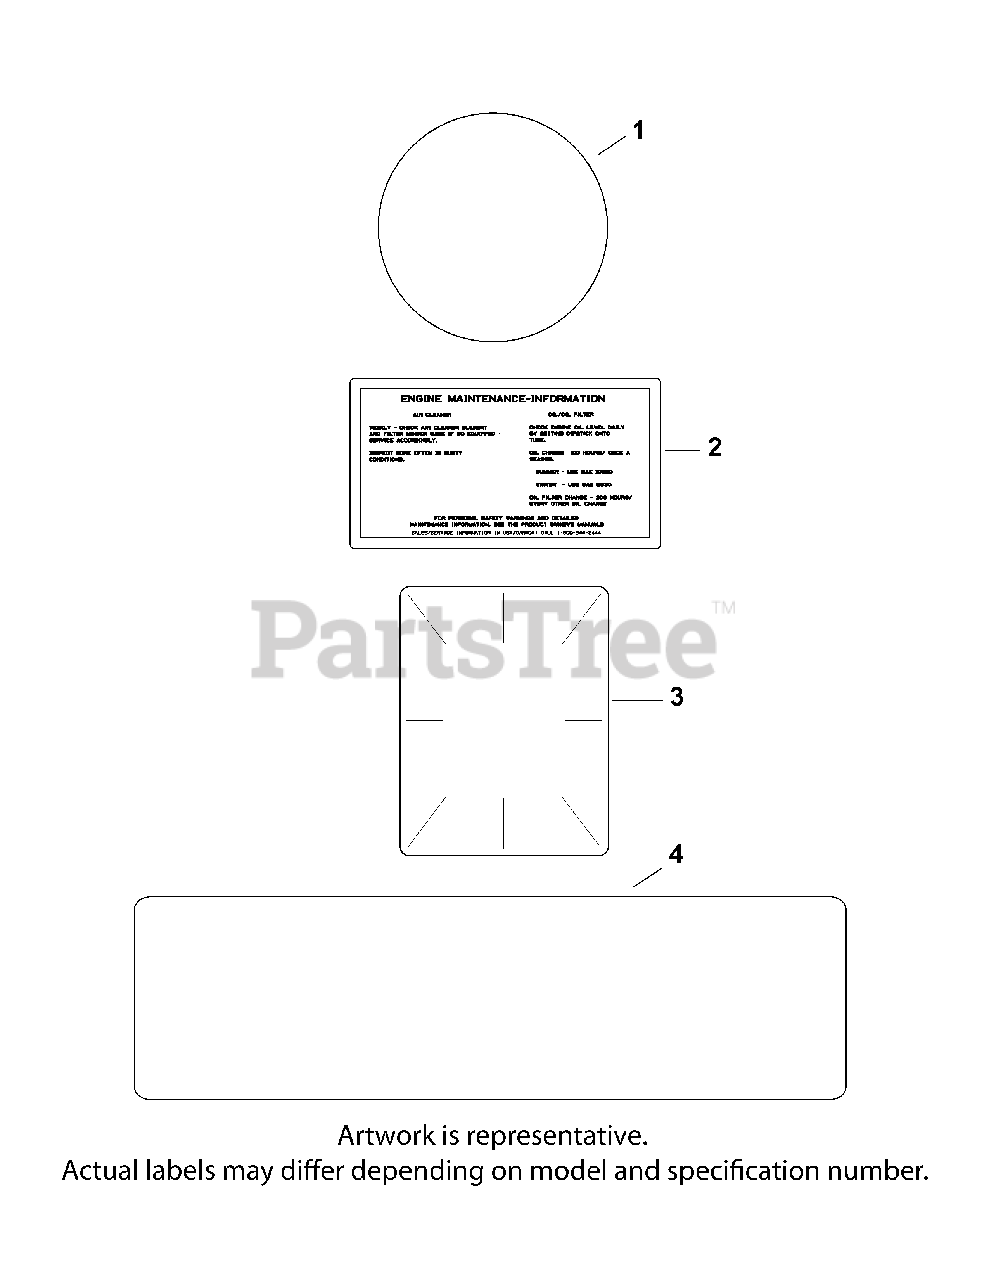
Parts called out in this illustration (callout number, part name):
1	Decal, Grass Screen
2	Decal, Air Cleaner
3	Decal, Clear Laminate
